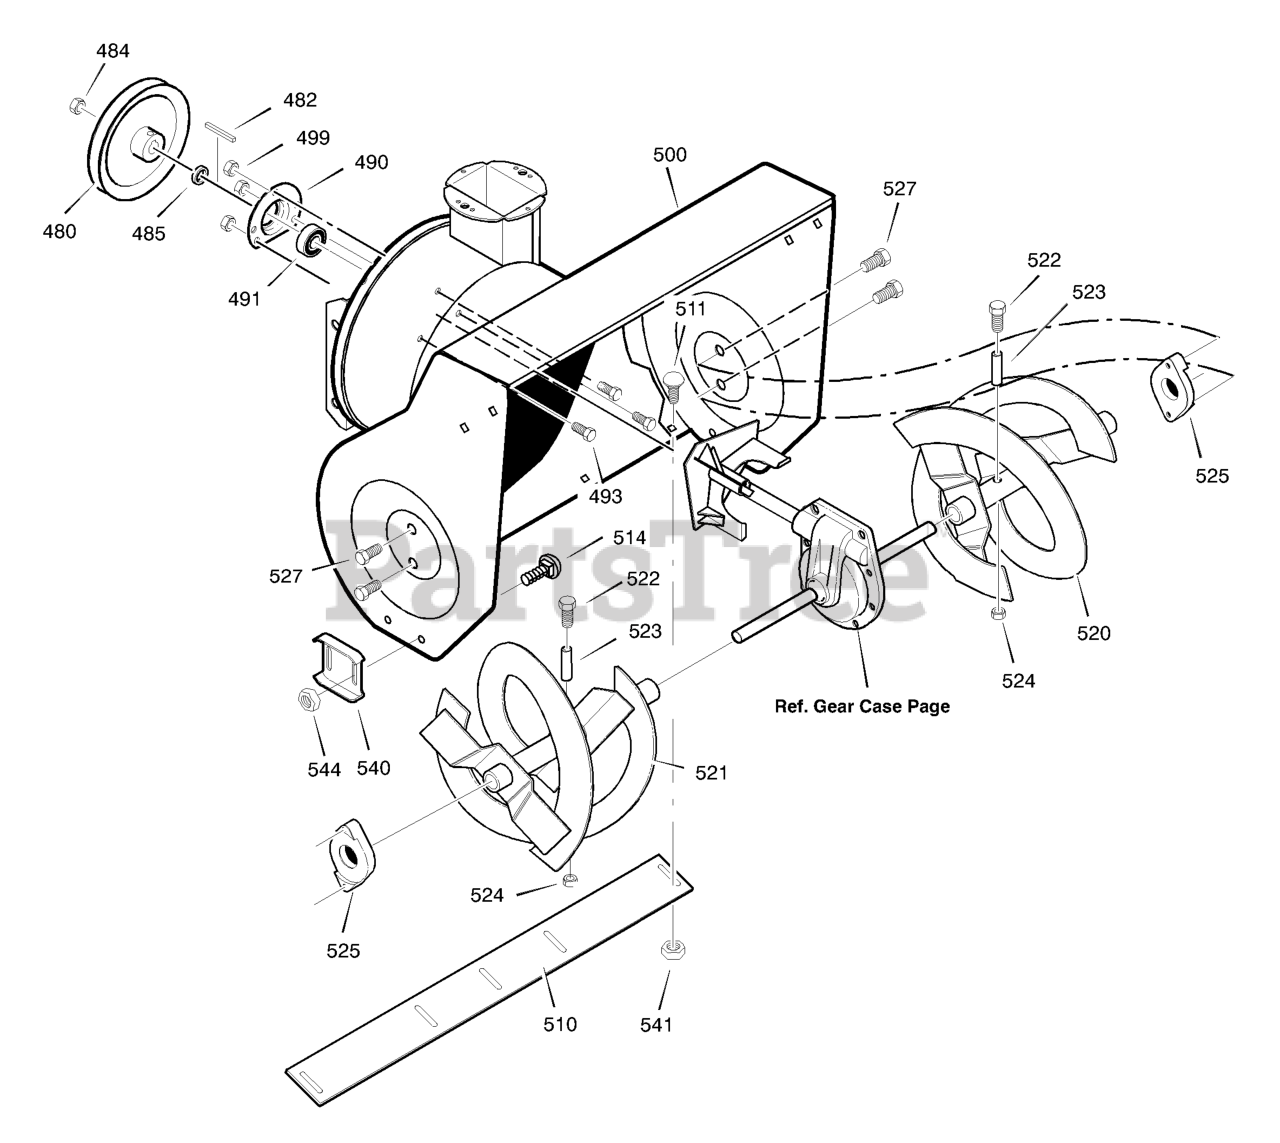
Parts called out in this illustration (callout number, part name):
480	PULLEY, 4L 8.40 OD
482	KEY, SQUARE 3/16 X 3/4
484	NUT, 1/2-20
485	SPACER, FRICTION PULLEY
490	RETAINER, BALL BRNG
491	BEARING, BALL
493	BOLT, HEX 5/16-18X .50
499	NUT, 5/16-18 HEXWDFLLK
500	HOUSING, ASSY
509	PLUG, CHRISTMAS TREE
510	BLADE, SCRAPER
511	BOLT, 5/16-18X.75
514	NUT, 5/16-18
520	AUGER, ASSY, LH
521	AUGER, ASSY, RH
522	SCREW, 1/4-20 X 1.75
523	SPACER, SLEEVE
524	NUT, 1/4-20
525	BEARING, FLANGE
527	SCREW, 5/16-18 x 0.75
540	SKID, HEIGHT ADJUST
541	BOLT, 5/16-18 X .75
544	NUT, 5/16-18
